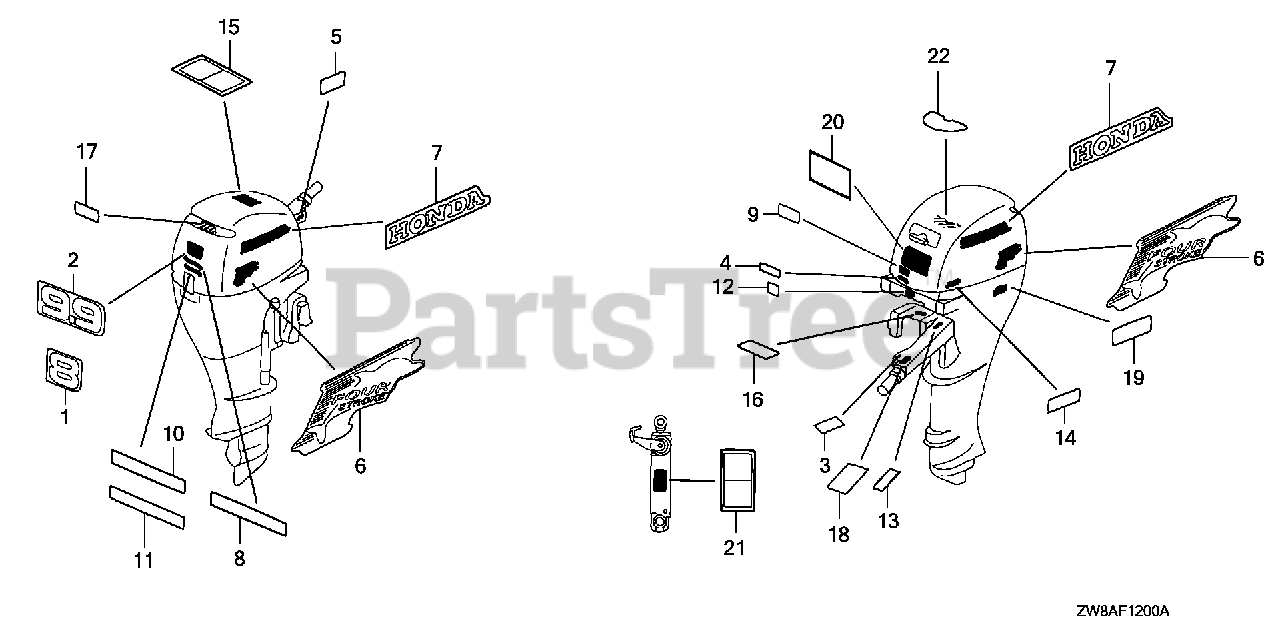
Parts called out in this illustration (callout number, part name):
2	MARK, RR. (9.9)
3	MARK, EMERGENCY SWITCH INDICATION
4	MARK, SPARE CLIP (ENGLISH)
5	MARK, STARTER (ENGLISH)
6	MARK, SIDE
7	MARK, SIDE STRIPE (HONDA)
8	MARK, POWER THRUST
9	MARK (E-SPEC)
11	MARK, POWER TILT
12	MARK, OIL PRESSURE
13	MARK, CHANGE
17	LABEL, OIL CAUTION (ENGLISH)
18	MARK, THROTTLE (ENGLISH)
19	LABEL, STORING CAUTION (ENGLISH)
20	LABEL, WARNING OPERATOR (ENGLISH)
22	MARK, EMERGENCY STARTER (ENGLISH)
